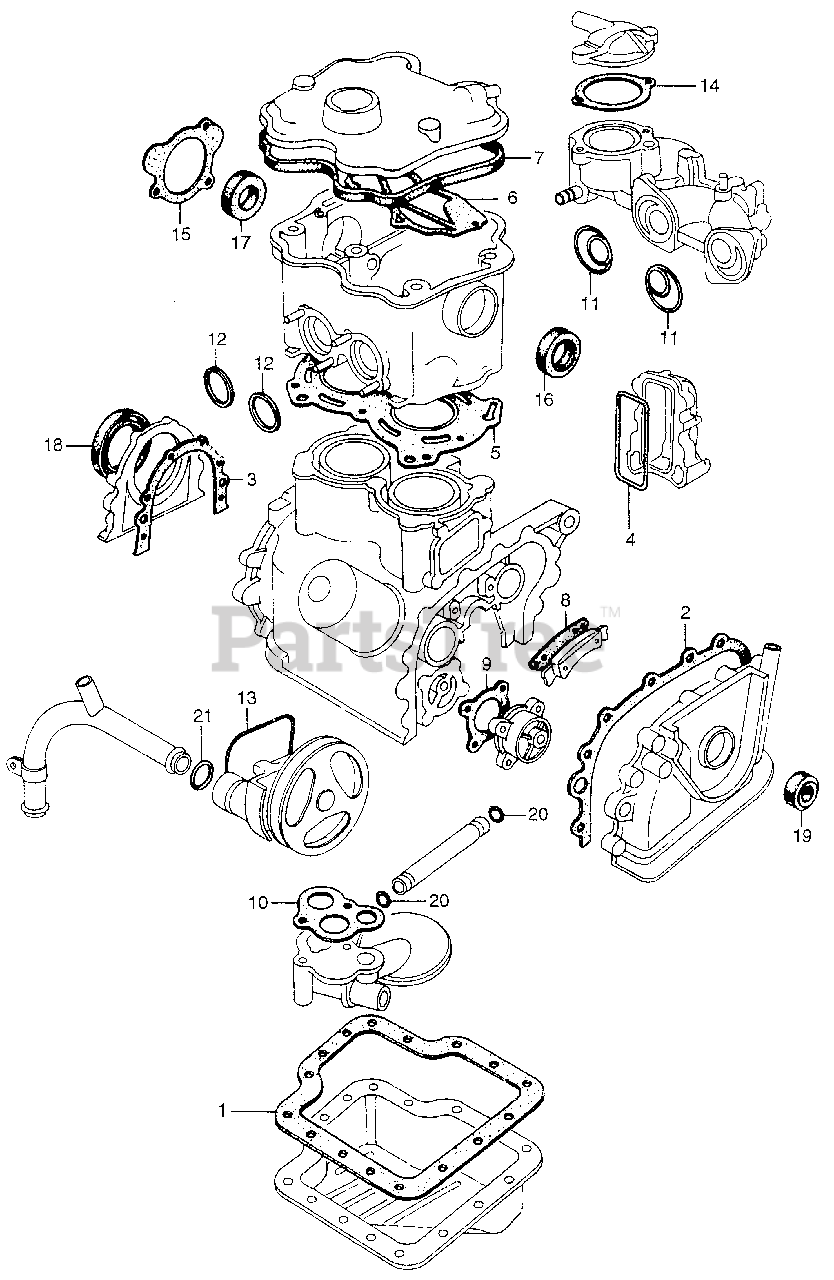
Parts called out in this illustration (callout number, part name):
1	GASKET, OIL PAN
2	GASKET, L.
3	GASKET, R. SIDE COVER
4	GASKET, BALANCER
5	GASKET, CYLINDER HEAD
6	GASKET, BREATHER
7	GASKET, HEAD COVER
8	GASKET, BALANCER CHAIN SLIPPER
9	GASKET, OIL PUMP
10	GASKET, OIL PASSAGE
11	GASKET, IN. MANIFOLD
12	GASKET, EX. PIPE
13	GASKET, WATER PUMP
14	COVER, THERMOSTAT
15	GASKET, BREAKER CASE
16	OIL SEAL (27X43X9) (NOK)
16	OIL SEAL (27X43X9)
17	OIL SEAL (22X36X6)
18	OIL SEAL (58X80X10) (NOK)
19	OIL SEAL (35X50X8)
20	O-RING (12.5X2.2)
21	O-RING (24.6X3.2)
